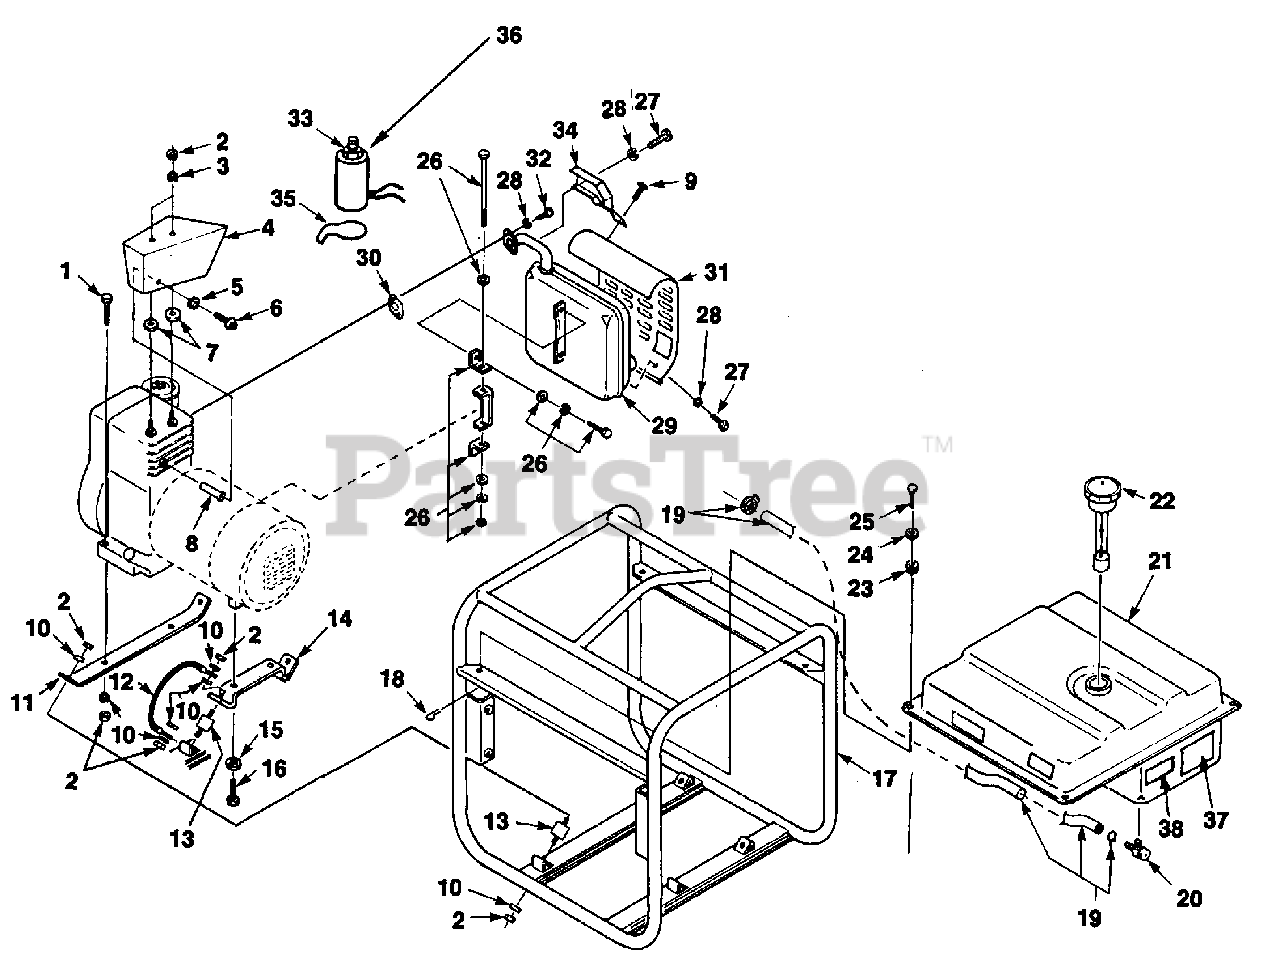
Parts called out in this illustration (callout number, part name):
1	SCREW- Cap hex hd. (5/16-18 x 1 3/4")
2	NUT- Hex (5/16-18)
3	WASHER- Lock
4	AIR DEFLECTOR
5	WASHER- Flat (#10)
6	SCREW- Mach. Rd. Hd. (10-24 x 1 1/2")
7	WASHER- Flat
10	WASHER- Int.Lock (5/16)
11	SUPPORT- Generator
12	GROUND STRAP
13	VIBRATION ISOLATOR
14	SUPPORT- Generator
15	WASHER- Lock/Int.
16	SCREW- Thd. forming (5/16-18 x 1")
17	ROLL CAGE
18	PIN- Cotter
19	FUEL LINE ASSEMBLY
20	FUEL VALVE
21	FUEL TANK
22	FUEL CAP
23	GROMMET- Isolator
24	WASHER- Flat
25	PIN- Clevis
26	MUFFLER BRACKET KIT
27	SCREW (1/4-20 x 1/2")
28	WASHER- Lock (1/4")
29	MUFFLER
30	GASKET- Muffler
31	SHIELD- Muffler
32	SCREW- Cap hex hd. (1/4-20 x 5/8")
33	NUT- Hex (1/4-28)
34	SHIELD- Exhaust
35	ARM- Throttle
36	ELECTROMAGNET
37	DECAL- Caution
38	DECAL- Fuel valve
